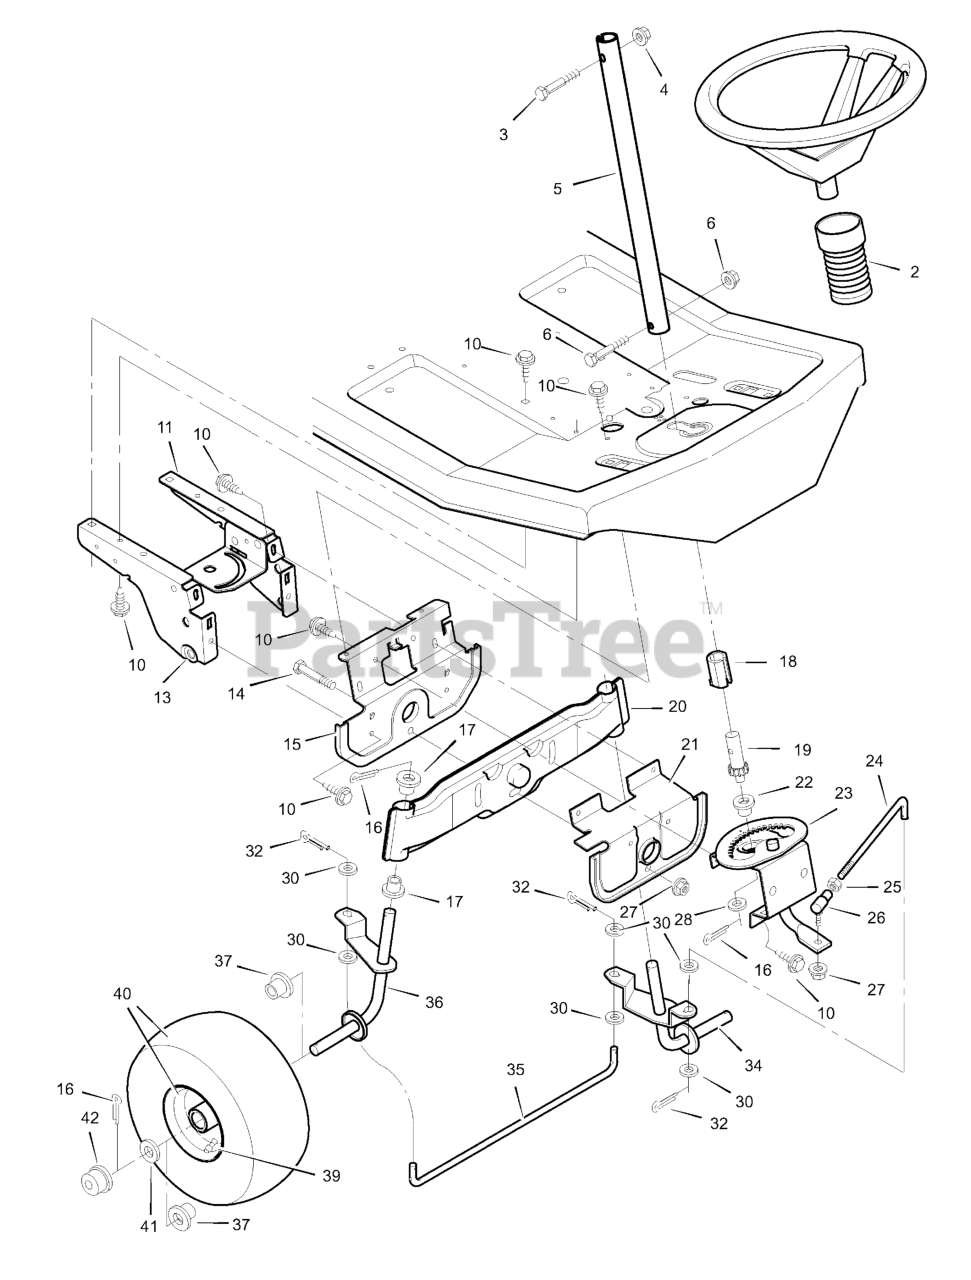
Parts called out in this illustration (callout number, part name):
1	Steering Wheel
2	Bellows, Steering Post
3	Bolt, Hex
4	Locknut, Flange
5	Post, Steering
6	Nut, Hex
9	Bolt, Carriage
11	Plate, Left Suspension
13	Plate, Right Suspension
14	Bolt, Hex
15	Support, Front Axle
16	Pin, Cotter
17	Bearing, Spindle
18	Adapter, Steering Post
19	Gear, Pinion
20	Axle Assembly, Front
21	Hanger Assembly, Front Axle
22	Bearing
23	Sector Assembly
24	Rod, Drag Link
25	Ball Joint, Steering
26	Nut, Hex
27	Locknut, Flange
28	Washer
30	Washer
32	Pin, Cotter
34	Spindle Assembly, Left
35	Rod, Tie
36	Spindle Assembly, Right
37	Bearing, Wheel
38	Tire Only
39	Valve Stem
40	Wheel & Tire Assembly
43	Hub Cap
